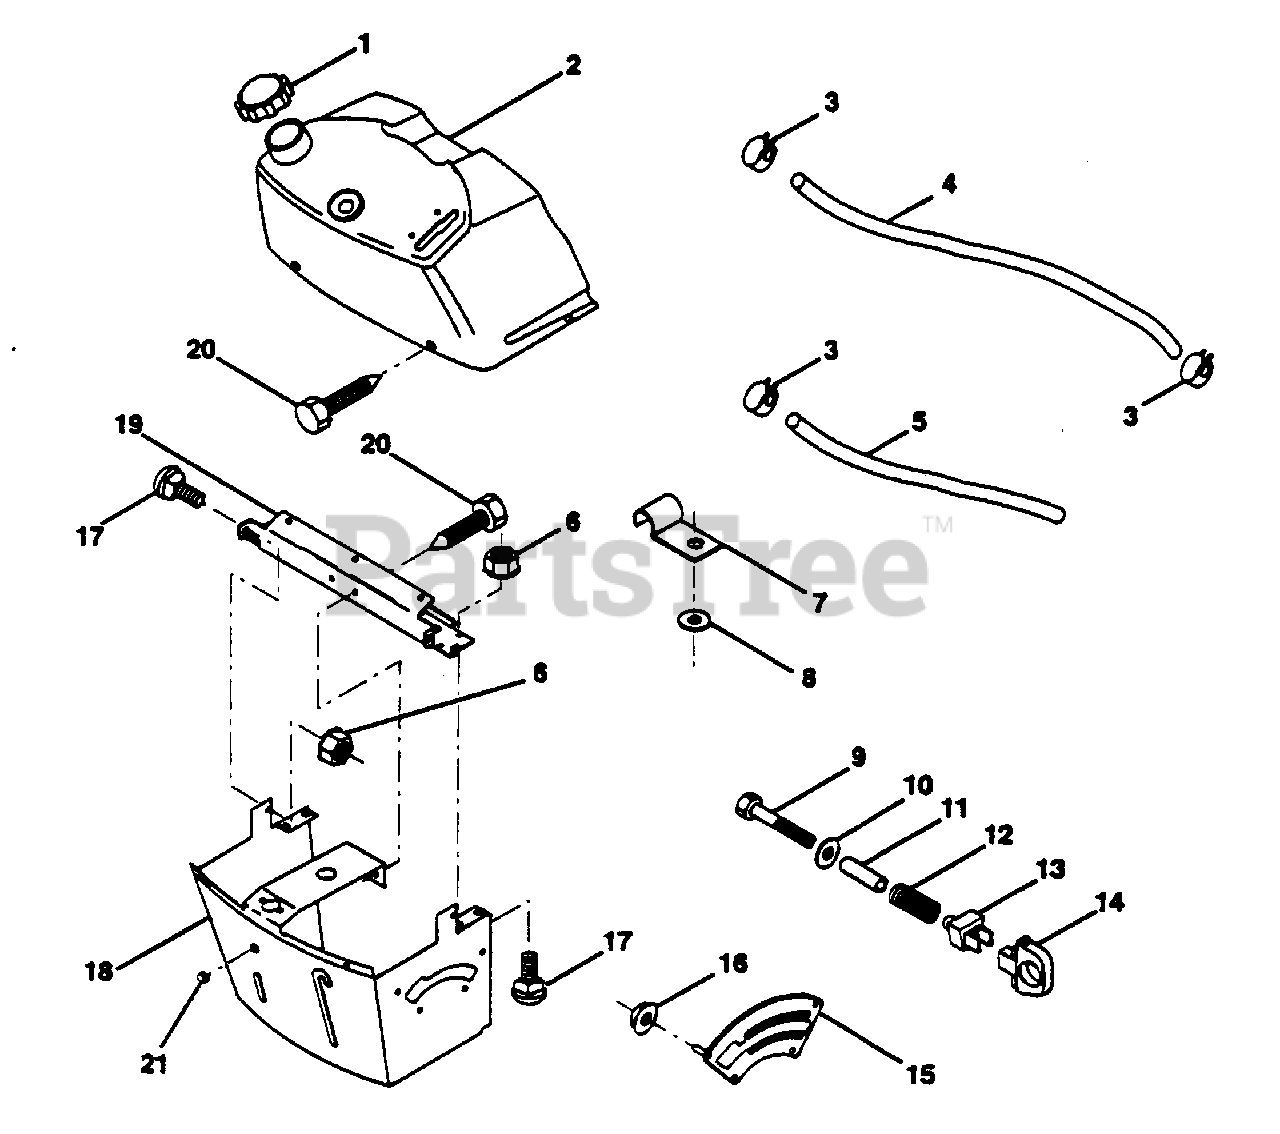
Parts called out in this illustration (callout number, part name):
1	Cap, Fuel (AYP part number)
2	Assembly, Dash & Fuel Tank (AYP part number)
3	Clamp, Hose (AYP part number)
4	Line, Fuel (AYP part number)
5	Line, Fuel (AYP part number)
6	Nut, Hex, Keps 1/4-20 (AYP part number)
7	Clip, Fuel Line (AYP part number)
8	Washer 9/32 x 3/4 x 16 Ga. (AYP part number)
9	Bolt, Hex, Fin 1/4-20 x 1-3/4 (AYP part number)
10	Washer 11/32 x 11/16 x 16 Ga. (AYP part number)
11	Spacer, Split (AYP part number)
12	Spring (AYP part number)
13	Clip, Height Adjustment (AYP part number)
14	Knob, Height Stop (AYP part number)
15	Adjustment, Quadrant Height (AYP part number)
16	Nut, Self-Threading 3/16-18 (AYP part number)
17	Bolt, Carriage 1/4-20 x 1/2 Gr. 5 (AYP part number)
18	Support Assembly, Dash (AYP part number)
19	Brace, Cross (AYP part number)
20	Screw, Self-Tapping 1/4-20 x 1/2 (AYP part number)
21	Plug Dome Black (AYP part number)
